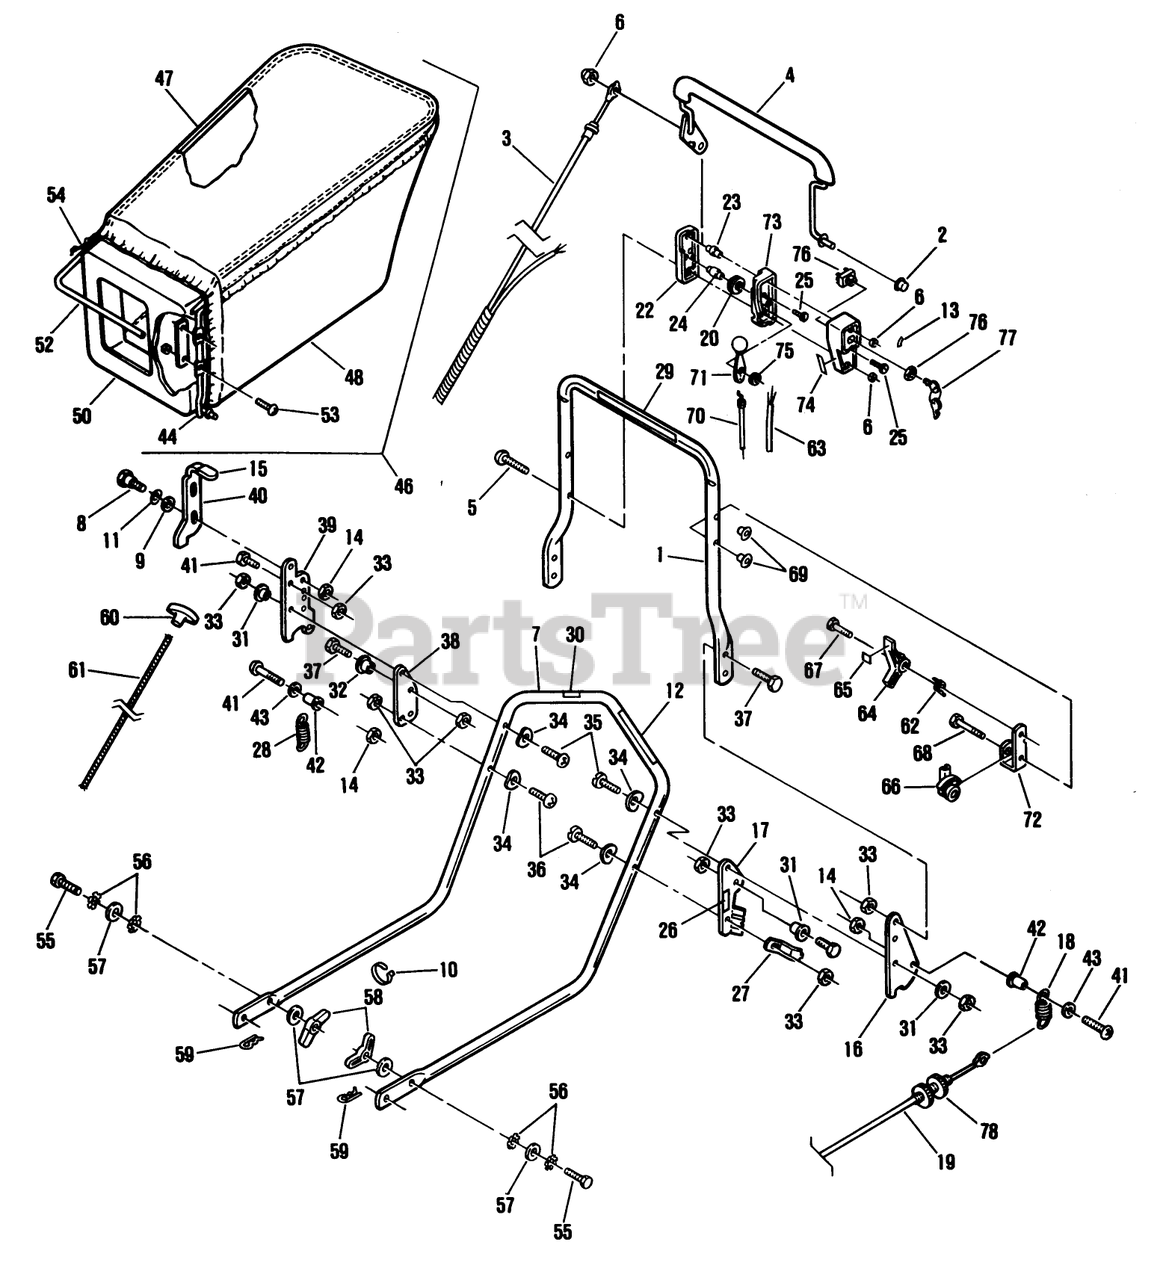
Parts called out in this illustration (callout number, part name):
3	CONTROL CABLE WES
5	SCREW
6	NUT C/LOCK E
8	BOLT RB&W
9	WASHER M
12	Decal-Starting Instructions
14	LOCKNUT E
15	KNOB (S&R)
18	SPRING
19	CABLE AY
20	PULLEY PL
23	COLUMN
24	PIN SKF
25	SCREW
33	NUT-LOCK F
34	WASHER-CURVED
35	SCREW LARSON
42	SPACER ROCKFORD
43	WASHER
47	HANGER BAG TROX
50	BAG ADAPTOR PL
51	LOCKNUT E
56	LOCK WASHER LARSON
57	WASHER
58	NUT-WING
60	HANDLE START UM&D
63	Wire Harness Assy.-Upper
68	BOLT QUALITY
70	CABLE TH'TTLE WES
71	LEVER&KNOB AY WES
75	WASHER-SPRING
76	SWITCH AY
